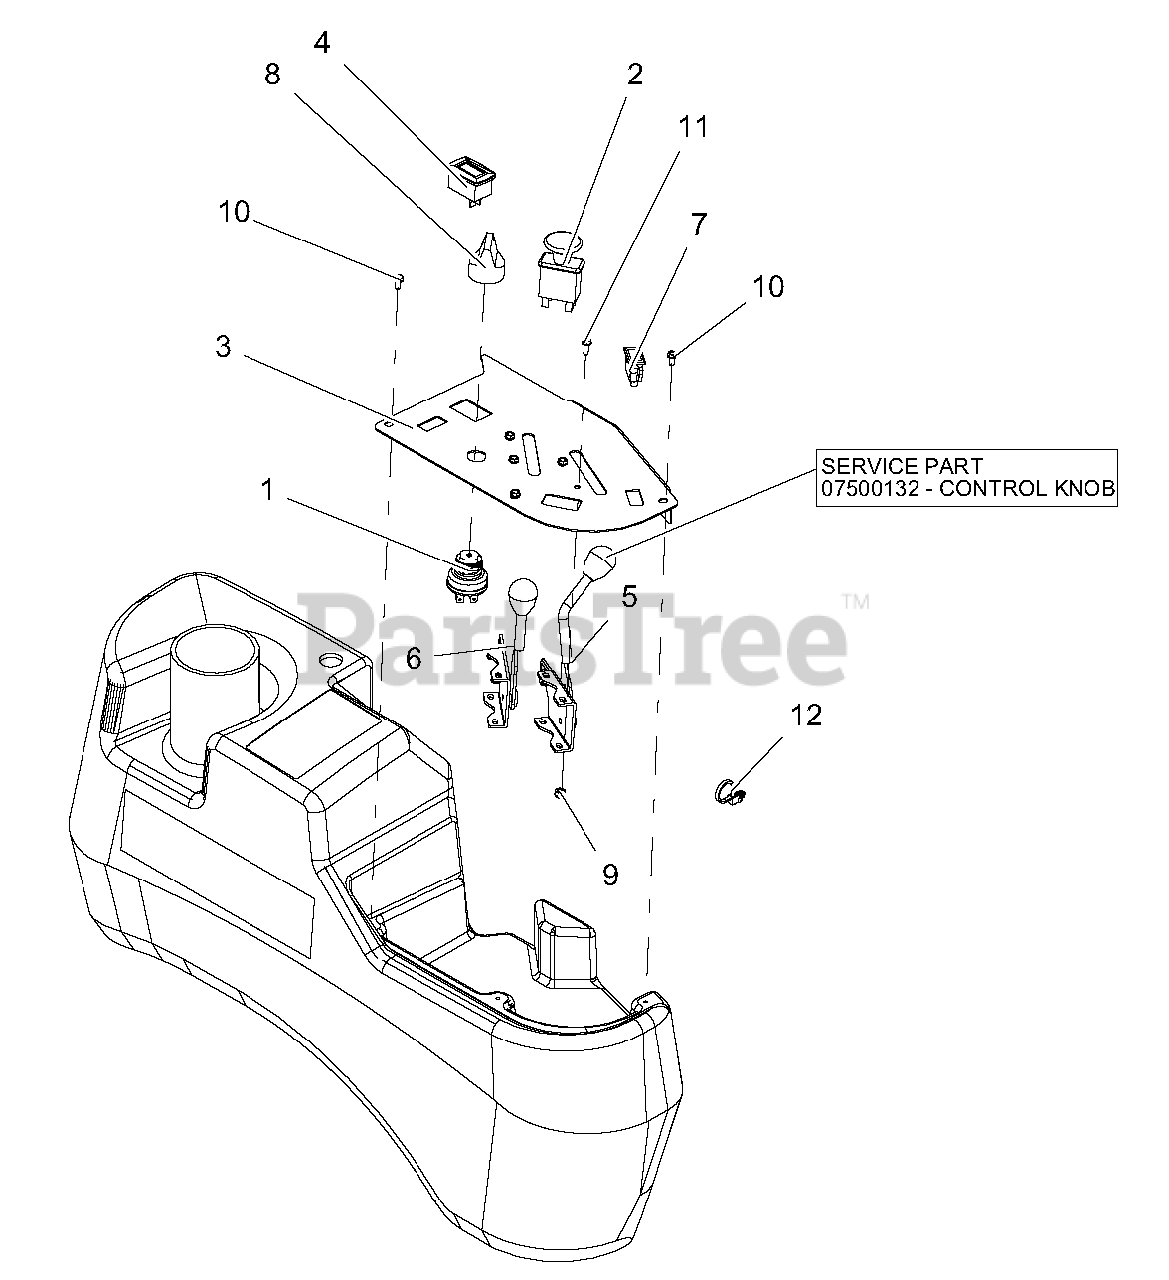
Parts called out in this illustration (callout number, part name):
1	SWITCH, IGNITION
2	SWITCH, CLUTCH
3	PANEL, CONTROL-BLACK
4	METER, HOUR W/MAINTENANCE
5	CABLE, PRO-CONTROL THROTTLE
6	CABLE, PRO-CONTROL CHOKE
7	LIGHT, INDICATOR
8	KEY, W/ COVER
9	@NUT-LK-NYL #10-24 YWZC
10	SCR-MCH 10-24X.38 HWHSTAINLESS
11	@SCR-MCH 10-24X.50 HWH YWZC
12	CABLE TIE W/ TREE (.25 HOLE)
